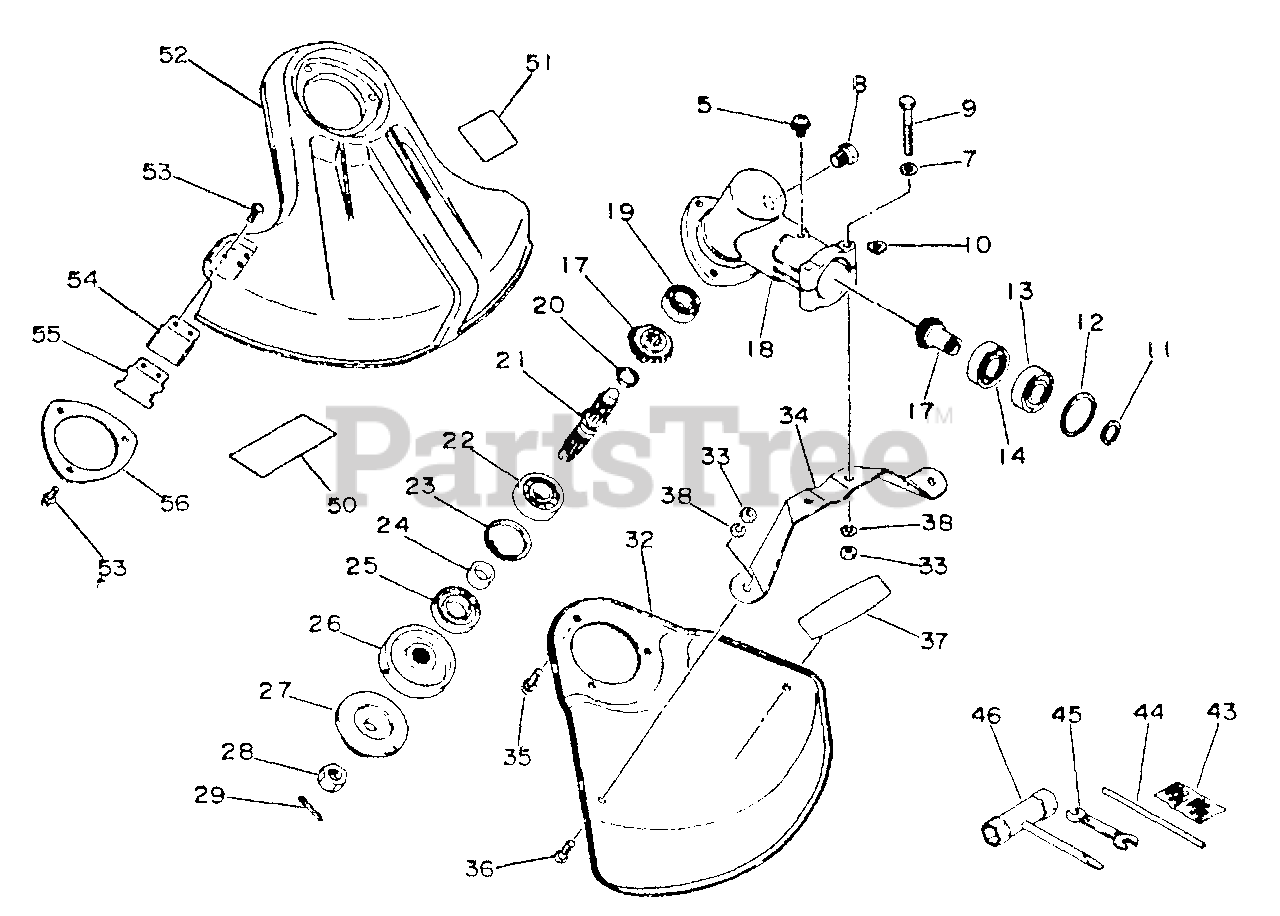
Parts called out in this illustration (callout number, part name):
5	SCREW 5×10
7	WASHER, FLAT 5.5×10×0.8
8	BOLT 8×8 SP
9	BOLT 5×40
11	RING, RETAINING - 12
12	RING, SNAP 28
13	BEARING, BALL 6001
14	BEARING, BALL 6001
17	GEAR SET
18	CASE, GEAR
19	BEARING, BALL 6000
20	RING, RETAINING - 12
21	SHAFT, GEAR
22	BEARING, BALL - 6201 C3
23	RING, SNAP Ø32
24	SPACER 11.8×15×9
25	SEAL, OIL 22
26	PLATE, ADAPTER - UPPER
27	PLATE, ADAPTOR - LOWER
29	PIN, COTTER 2×22
32	SHIELD
33	NUT M5
34	BRACKET, SHIELD
35	SCREW 5×10
36	SCREW 5×8
37	LABEL - ECHO
38	WASHER, SPRING 5
43	PIN, COTTER 2×22 (PKG. OF 10)
44	TOOL, LOCKING 5×120 MM
45	SPANNER 8×10
46	T-WRENCH 17x-19 L200
50	LABEL, ECHO
51	LABEL - CAUTION
52	SHIELD ASSY
53	KNIFE, TRIMMER LINE
54	PROTECTOR
55	SCREW 5×16
56	PLATE, SHIELD Ø49.5 MM
